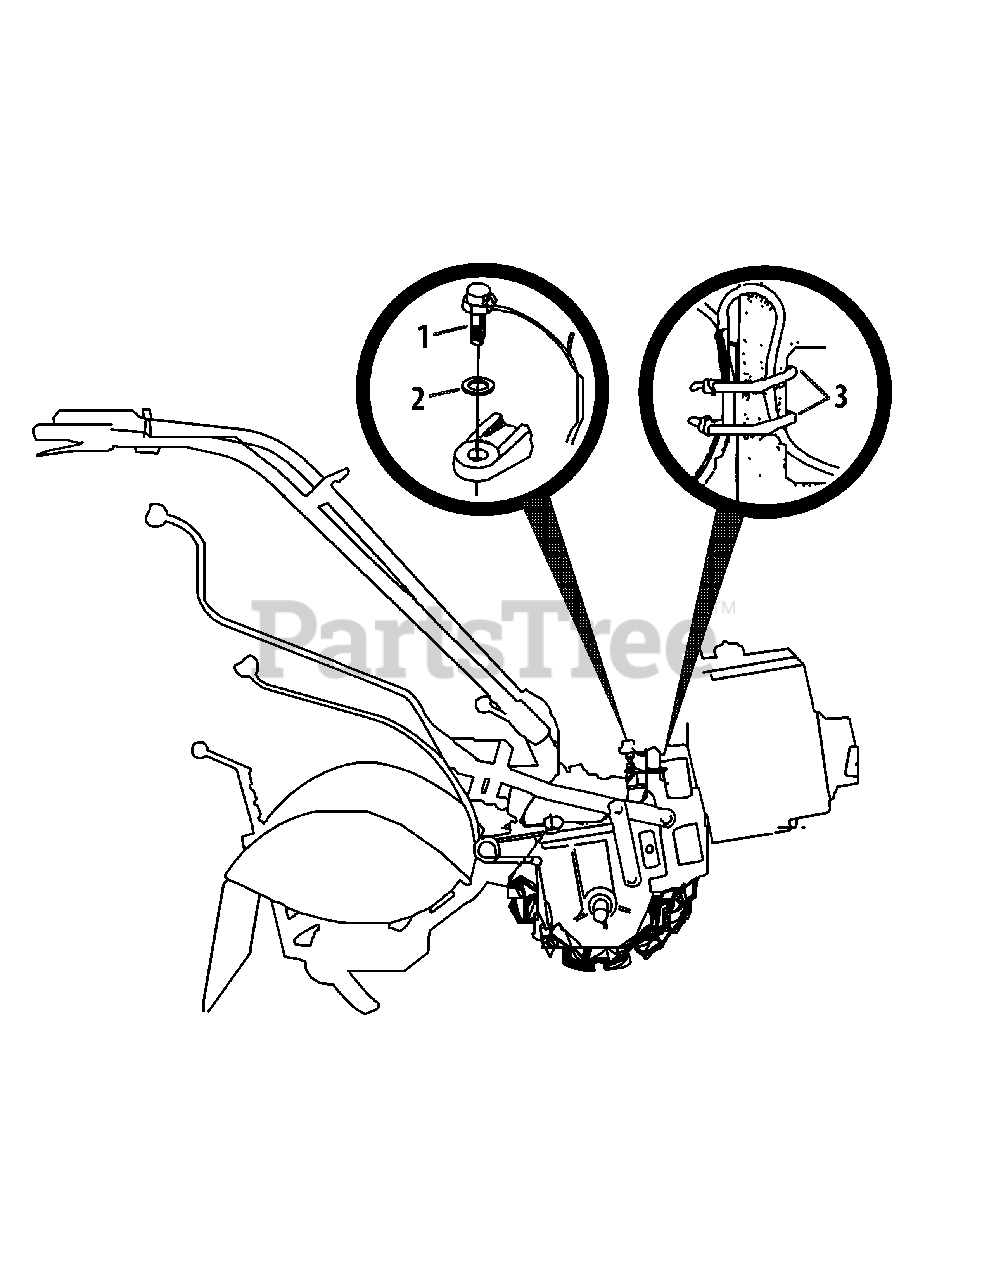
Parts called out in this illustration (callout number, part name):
1	PTO Switch
2	Internal L-Washer, 9/16"
3	Plastic Tie
